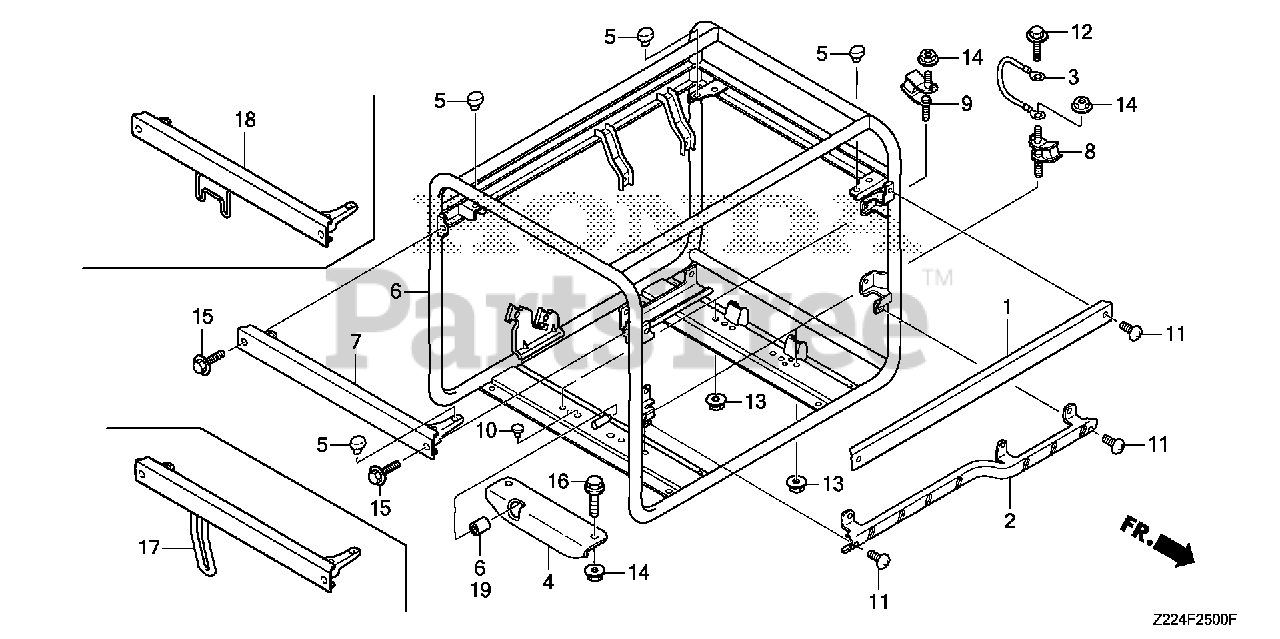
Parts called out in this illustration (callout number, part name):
3	CABLE, SUB-GROUND
4	BRACKET, STOPPER
5	RUBBER, FUEL TANK MOUNTING
6	FRAME *NH105* (COO) (MAT BLACK)
8	RUBBER (LOWER)
9	RUBBER (LOWER)
10	RUBBER, BUMP STOP
12	BOLT, GROUND (6X16) (WASHER 12.5MM) (ZN)
13	NUT, FLANGE (8MM)
14	NUT, FLANGE (10MM)
15	BOLT, FLANGE (8X16)
16	BOLT, FLANGE (10X40)
18	FRAME, SIDE *NH105* (COO) (MAT BLACK)
19	BOOT, COLUMN STOPPER
